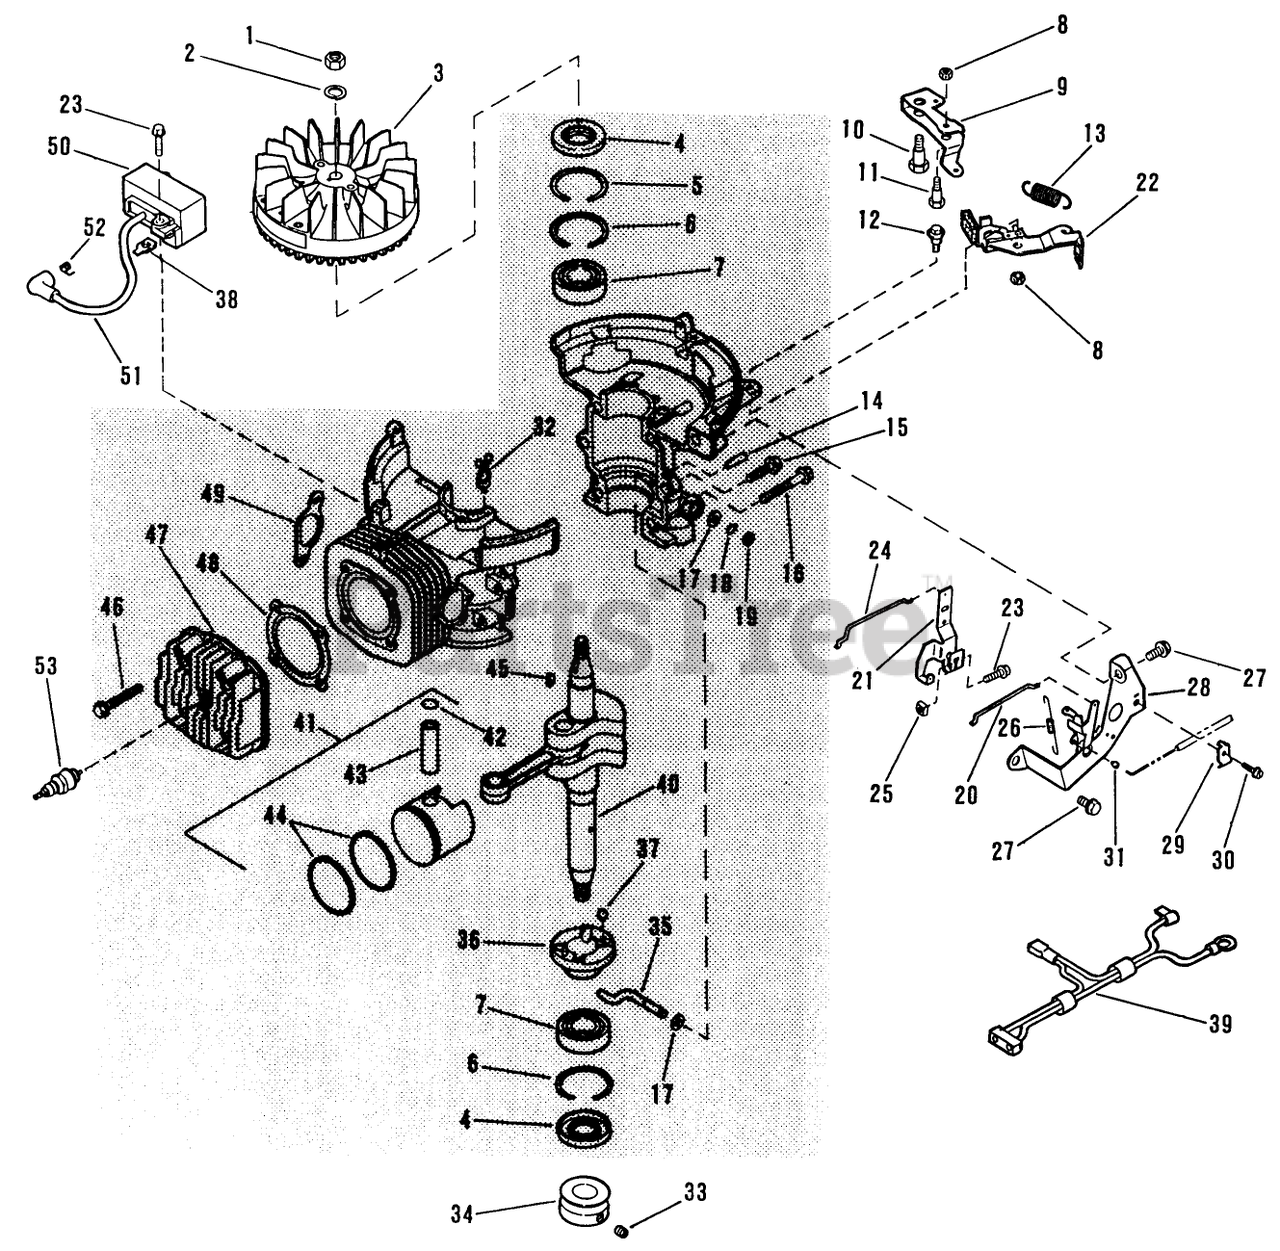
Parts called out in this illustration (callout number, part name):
1	NUT
4	SEAL - OIL SM
5	RING-RETAINER SM
7	BEARING-BALL SM
8	LOCKNUT E
9	ACT.BRAKE LVR. SM
10	SCREW-SHOULDER
13	SPRING-BRAKE
15	SCREW-H.W.HD. F
16	SCREW-HEX W.H. SM
18	RING-RETAINING
19	SEAL - OIL SM
23	SCREW
24	ROD-THROTTLE SM
26	SPRING-GOV. SM
28	GOVNR BRKT SM
32	WIRE TIE SM
34	PULLEY-ENGINE
44	RING SET S
45	KEY
46	SCREW
47	CYLINDER HEAD SM
49	GASKET - EXH SM
51	HI-TENS.LEAD
